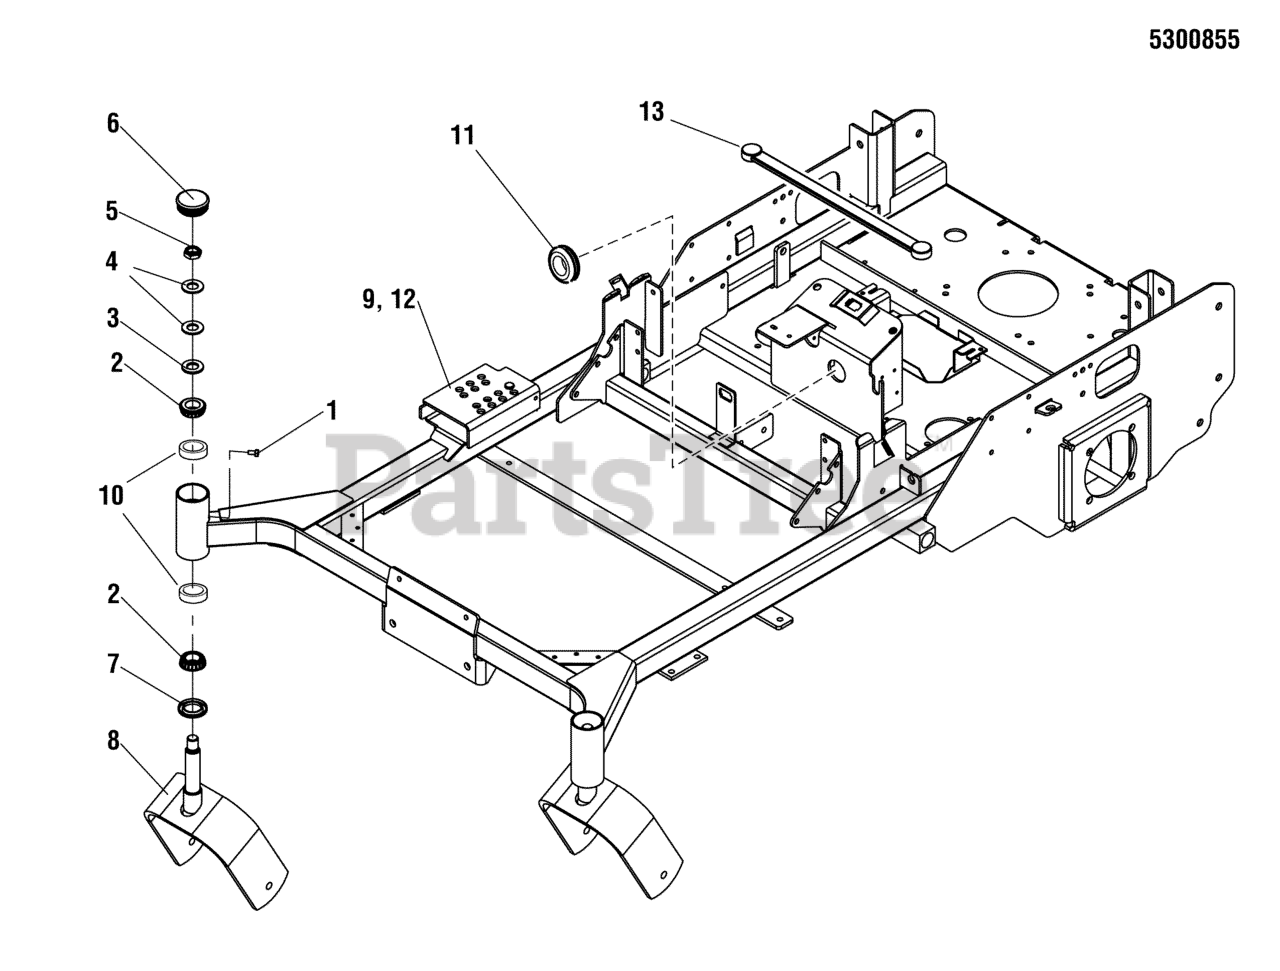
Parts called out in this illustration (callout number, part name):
1	BOLT, 1/4-28 X 1/2, GD5 YZ
2	BEARING, TAPERED ROLLER, 1"
3	WASHER, 3/4 SAE
4	WASHER, BELLEVILLE - 1.500 X .755
5	NUT, 3/4-16, HEX JAM NYLON LOCK
6	CAP, GREASE, LOW PROFILE
7	SEAL, GREASE
8	WELD, CASTER YOKE - RED
9	WELD, MAIN FRAME SNP 61" - RED
10	CUP, BEARING (SV)
11	GROMMET, 1-1/4
12	WELD, MAIN FRAME SNP 72" - RED
13	STRAP-BLACK RUBB
